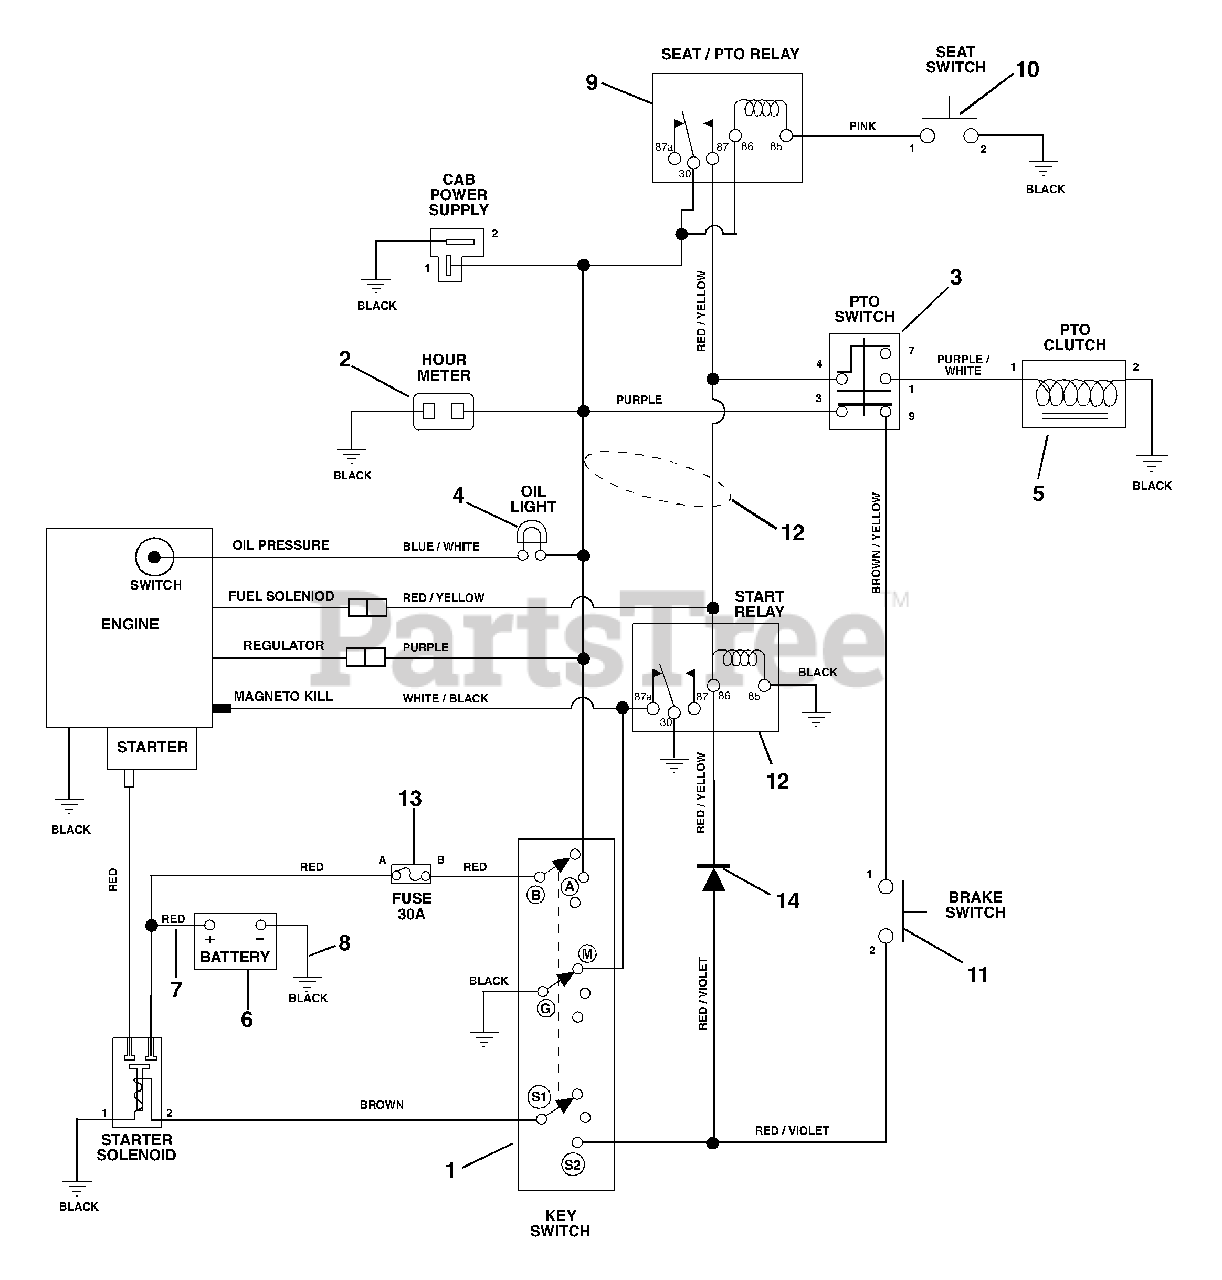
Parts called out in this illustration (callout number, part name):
1	Key Switch
2	Hour Meter
3	Switch-Clutch With Retainer Ring
4	Light-Indicator
5	Electric Clutch
6	Battery with Tube
7	Cable-Battery To Solenoid
8	Ground Cable
9	Relay
10	Seat Switch
11	Switch-Single Pole
12	Harness-Briggs Wiring
14	Molded Diode Plug-Black 1-Amp
